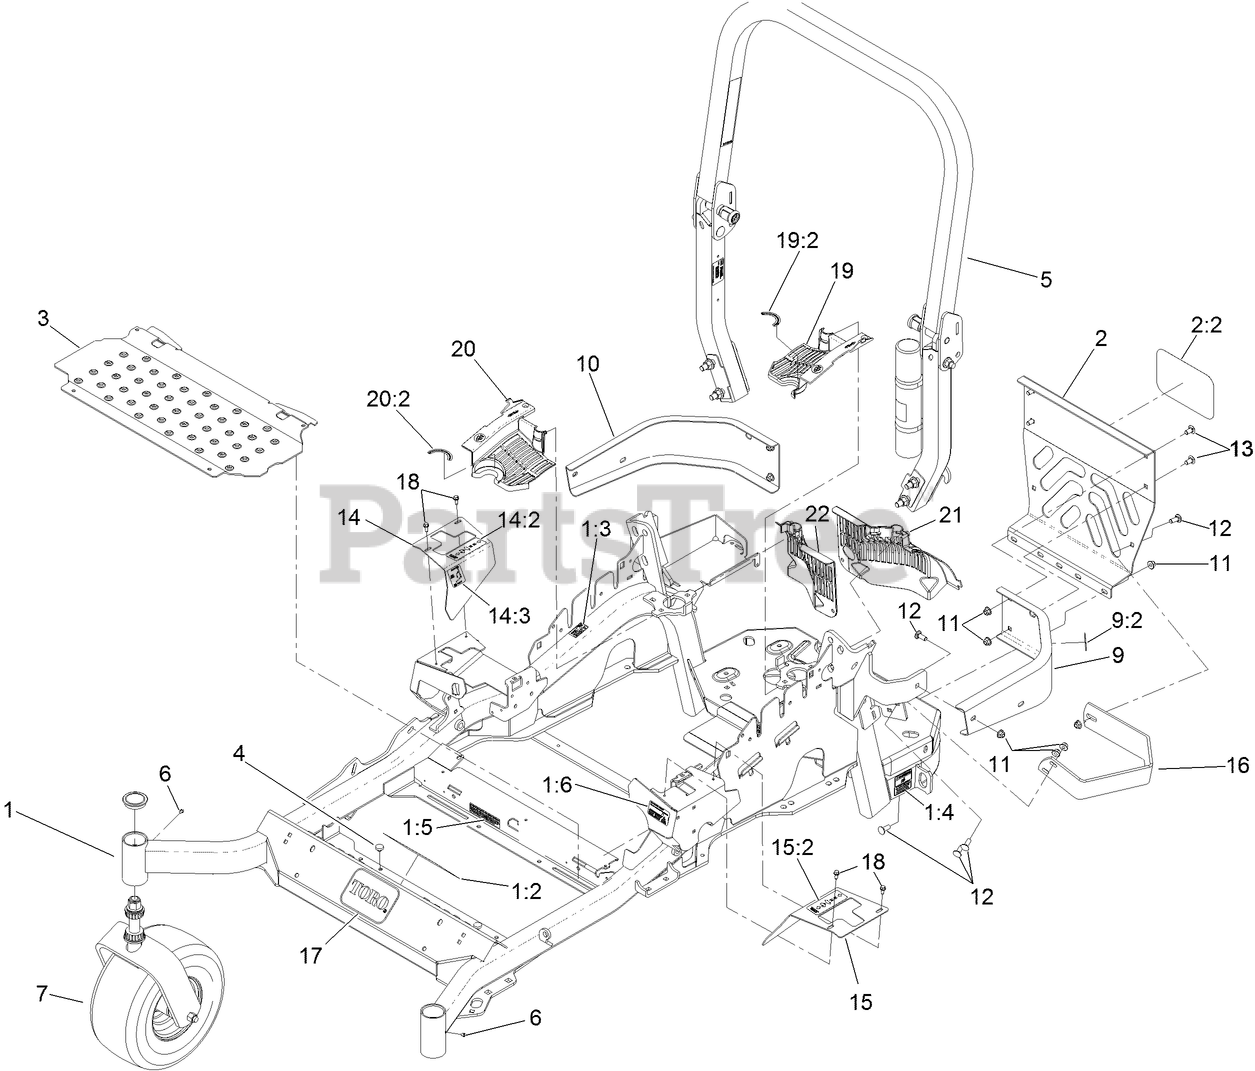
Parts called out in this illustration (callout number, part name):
1	MAIN FRAME ASM
1:2	DECAL-SLOPE
1:3	DECAL-CAUTION
1:4	DECAL-BELT DRIVE
1:5	DECAL-ARRESTER, SPARK
1:6	DECAL-FUEL FILL
2	REAR GUARD ASM
2:2	DECAL
3	FLOORPAN
4	BUMPER
5	ROPS ASM
7	Caster Wheel ASM
9	BUMPER-REAR, LH
9:2	DECAL-CAUTION
10	BUMPER-RH
11	NUT-HF, NI
12	SCREW-CARR
13	SCREW-CARR
14	RH MOTION CONTROL COVER ASM
14:2	DECAL-MOTION CONTROL
14:3	DECAL-PARK BRAKE
15	LH MOTION CONTROL COVER ASM
15:2	DECAL-MOTION CONTROL
16	GUARD-MUFFLER
17	DECAL
18	SCREW-HWH
19	LH HYDRO GUARD ASM
19:2	DECAL-HYDRO OIL
20	RH HYDRO GUARD ASM
20:2	DECAL-HYDRO OIL
21	GUARD-HYDRO, REAR (LH)
22	GUARD-HYDRO, REAR (RH)
